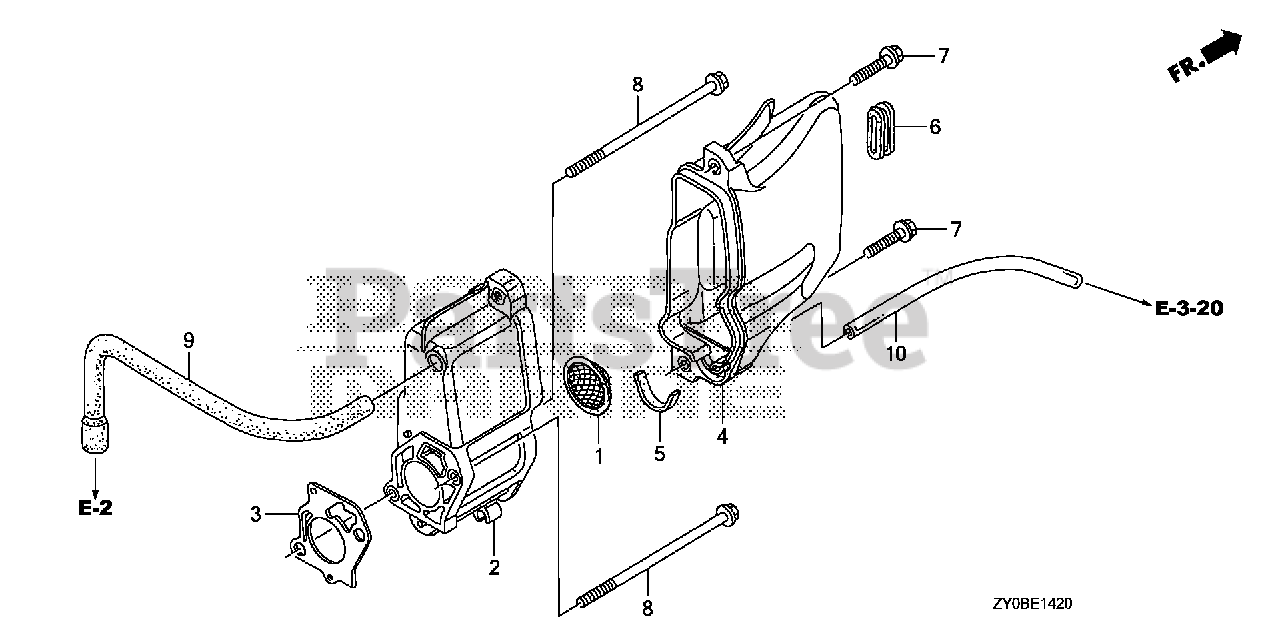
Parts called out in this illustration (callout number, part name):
1	TRAP, FLAME
2	PLATE, MUFFLER
3	GASKET, MUFFLER PLATE
4	COVER, MUFFLER
5	GASKET, MUFFLER COVER
6	RUBBER A, TANK MOUNTING
7	BOLT, FLANGE (6X22)
8	BOLT, FLANGE (6X106)
9	TUBE, BREATHER
10	BULK HOSE, VINYL (4X7X8000) (4X7X120)
